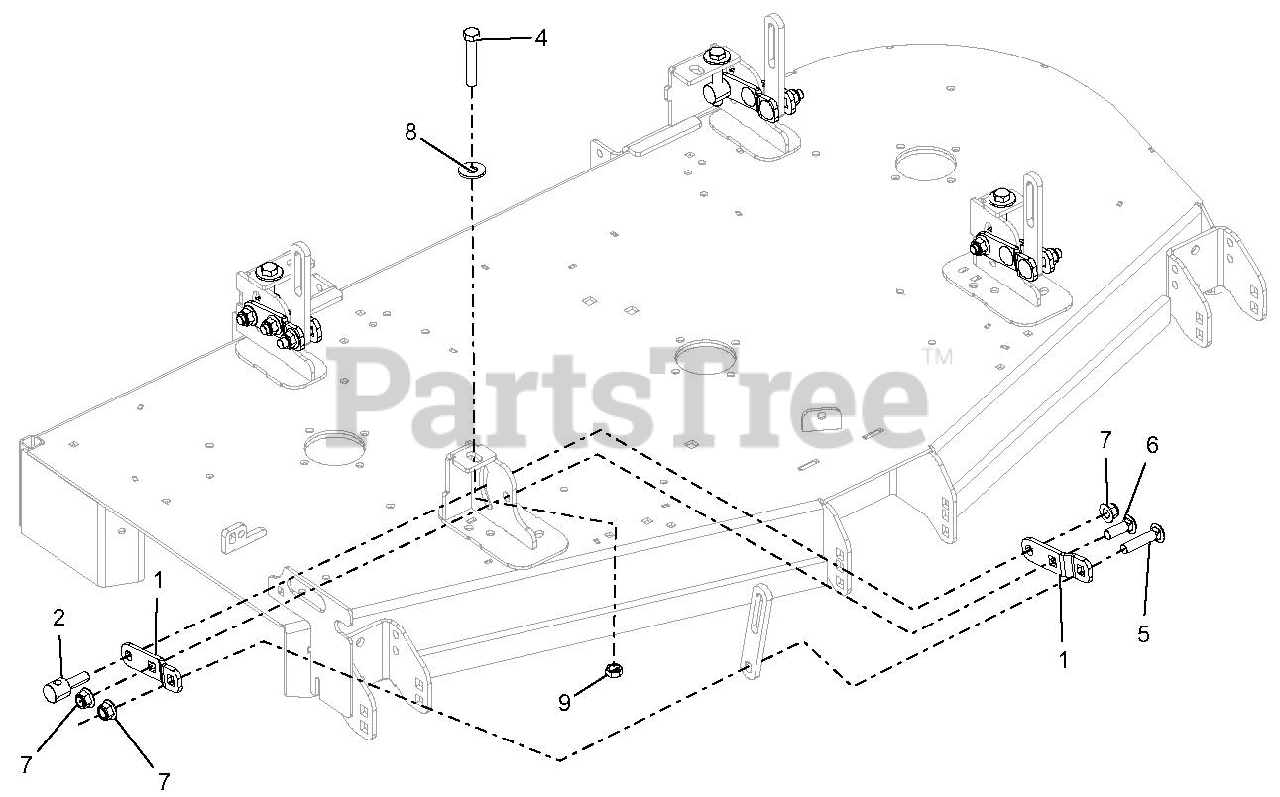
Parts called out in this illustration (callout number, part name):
1	BRKT, DECK LEVELING
2	TRUNNION, .50-13
4	BLT-HEX .50-13X3.00 GR5 FTH YWZC
5	BLT-RDHDSQNK .50-13X2.25 G5 Y
6	BLT-RDHDSQNK .50-13X1.50 G5 YWZC
7	NUT-LK-NYL-FLG .50-13 YWZC
8	WSHR-FL-STL.563X1.38X.109YWZC
9	NUT, JAM .500-13 YWZC
